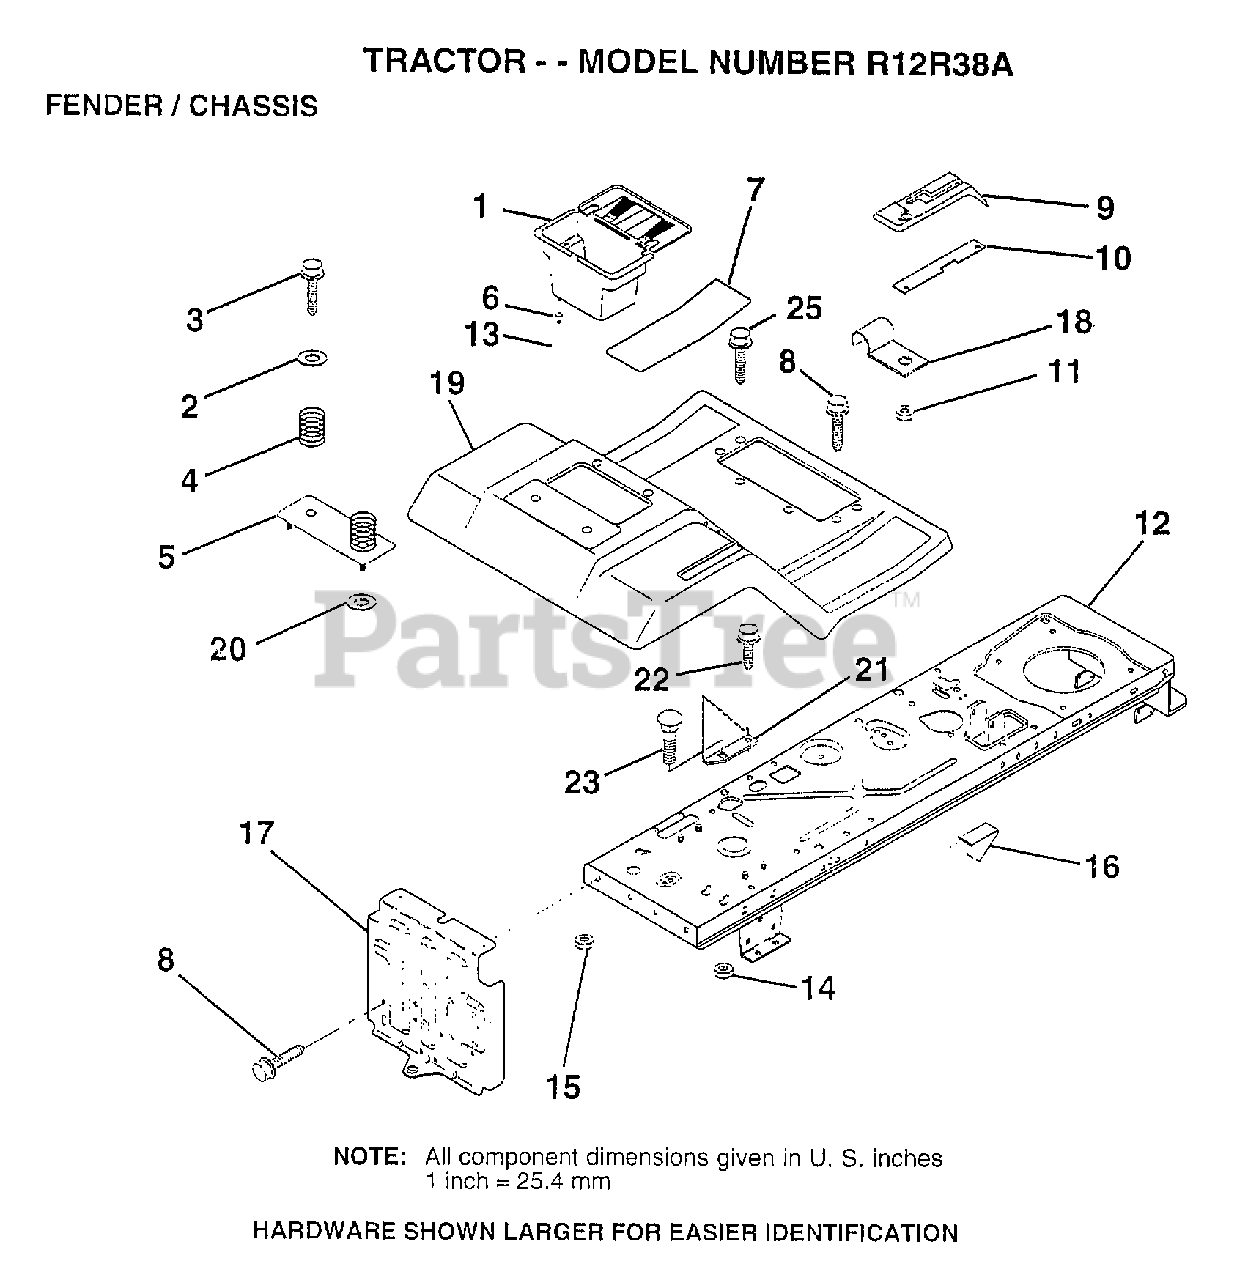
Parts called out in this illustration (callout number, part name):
2	WASHER
3	SCREW
4	SPRING COMPRESSIO
5	BTRY FENDER PLATE
6	HOSE CLAMP T
7	PAD FOOTREST
8	SCREW
10	PLATE LOCK SHIFT
11	NUT
12	CHASSIS.WELD.ASM.
13	TUBE T
15	NUT HXKEP 1/4X20
17	DRAWBAR ASM LR
18	"CLIP,INSULATOR"
19	FENDER/FOOT MS505
21	BRACKET STOP DEPT
22	SCREW LT
25	SCREW
